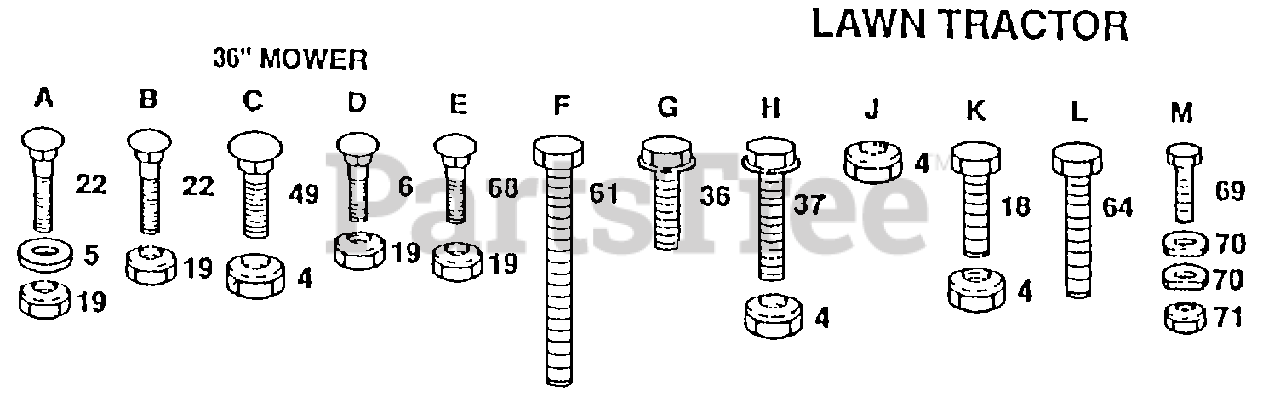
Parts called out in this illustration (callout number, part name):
5	WASHER M
6	BOLT
22	BOLT
36	SCREW
37	SCREW
49	BOLT
61	BOLT
64	BOLT.3/8-14X1.25
69	BOLT LT
70	WASHER T
